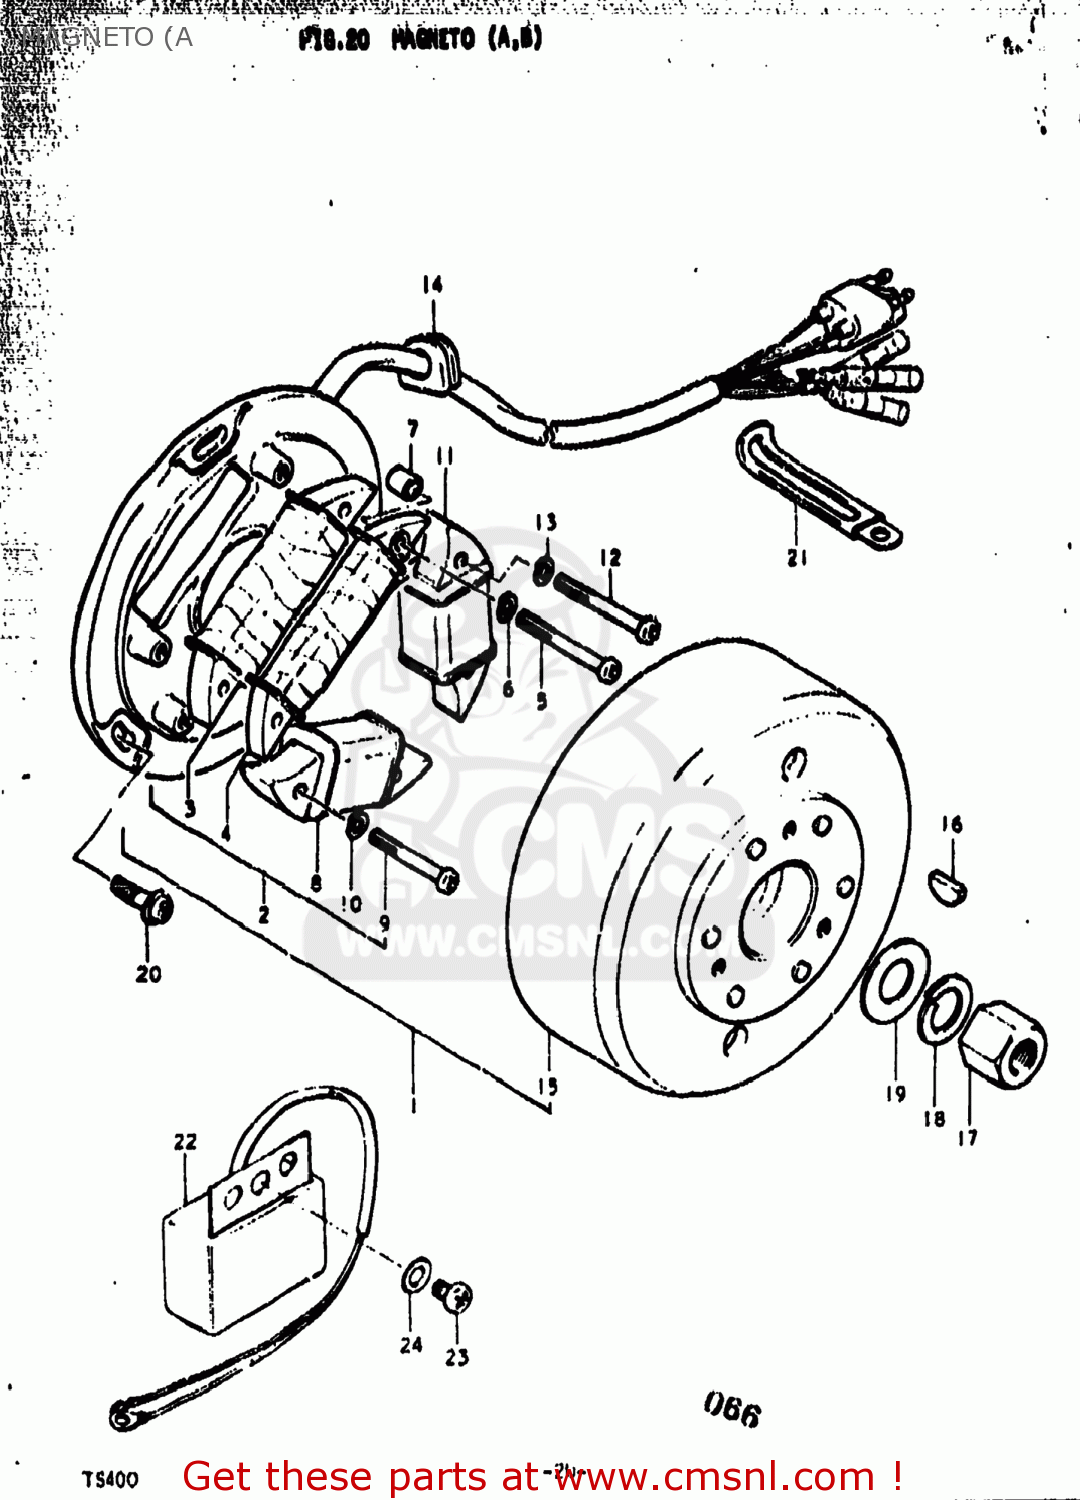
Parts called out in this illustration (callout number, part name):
1	MAGNETO ASSEMBLY
2	STATOR ASSEMBLY
3	COIL
4	COIL,PULSER
5	SCREW 5X35
6	LOCK WASHER
7	COIL ASSEMBLY,PICK-UP
8	COIL
9	SCREW
10	LOCK WASHER
11	COIL,CHARGE
12	SCREW 5X35
13	LOCK WASHER
15	ROTOR ASSEMBLY
16	KEY 4MM
17	NUT
18	LOCK WASHER
19	WASHER(14X27X3)
20	SCREW(5X14)
21	CLAMP
22	REGULATOR ASSEMBLY
23	SCREW
24	WASHER
